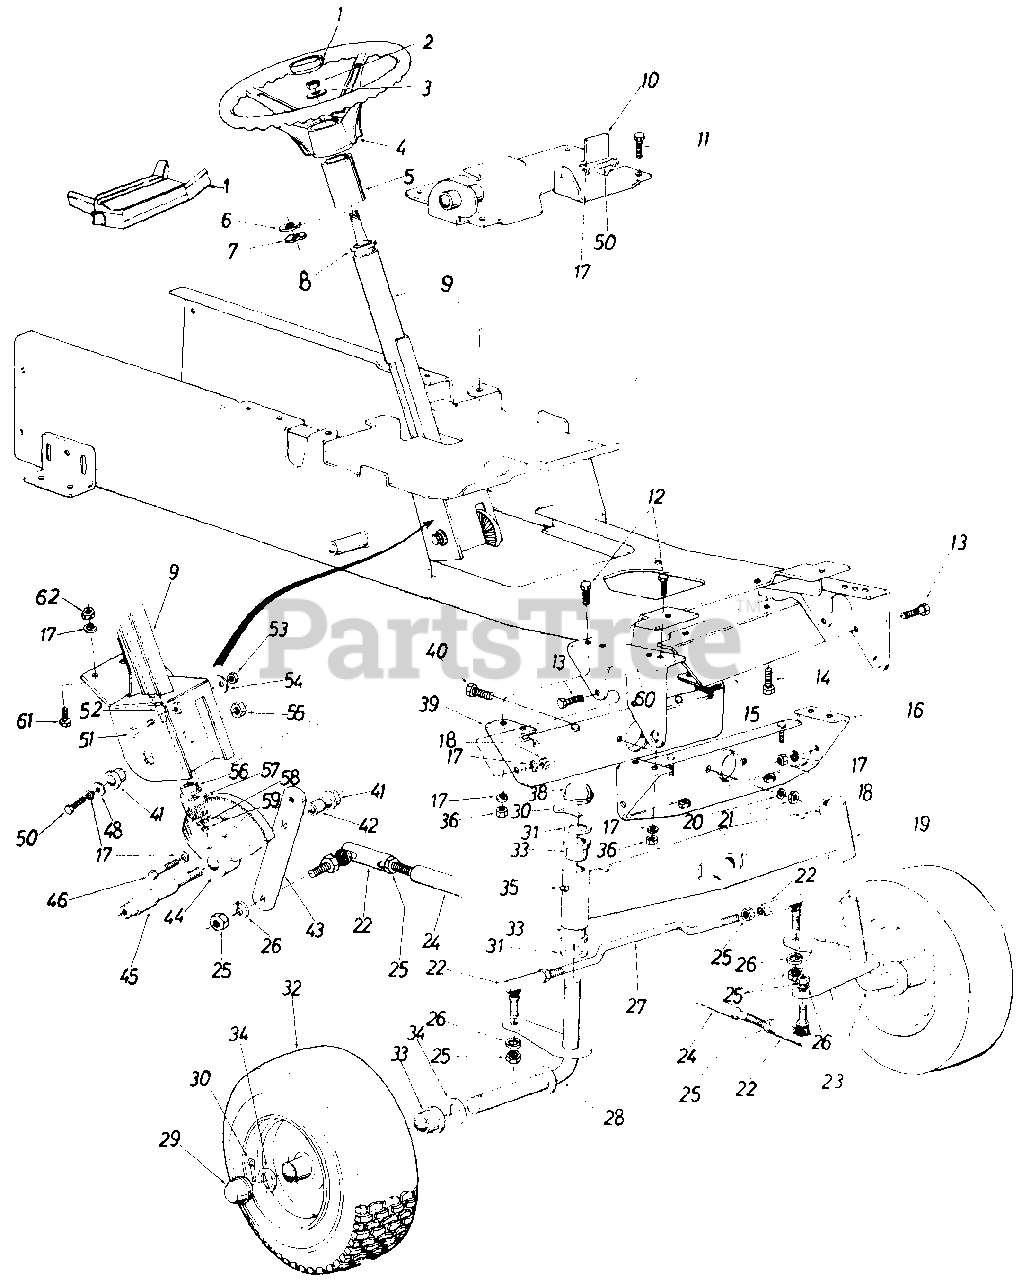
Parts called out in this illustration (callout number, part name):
1	Steering Wheel Cap
2	Hex Cent. L-Nut 5/16-18 Thd.
3	Bell-Wash.
4	Steering Wheel
5	Steering Tube - Outer
6	Double "D" Fl-Wash.
7	Wave Wash. .660" I.D. x .88" O.D.
8	Ball Brg. .63" I.D. x 1.38" O.D.
10	Dash Panel Base Plate Ass'y.
11	Hex Self-Tap Scr. 3/8-16 x .75" Lg.
12	Hex Bolt 3/8-16 x 1.50" Lg.
13	Hex Bolt 3/8-16 x 1.00" Lg.
14	Hex Wash. S.F. Tap Scr. 3/8-16 x 1.25" Lg.
15	Dust Shield
18	Hex Nut 3/8-16 Thd.
19	Pivot Bar Ass'y.
20	Bell-Wash. 3/8" I.D.
21	Hex Cent. L-Nut 3/8-16 Thd.
22	Drag Link End
23	Axle Ass'y.- L.H.
24	Drag Link
25	Hex Nut 1/2-20 Thd.
26	L-Wash. 1/2" I.D.
27	Tie Rod
28	Axle Ass'y.- R.H.
29	Hub Cap
30	Cotter Pin 3/16" Dia. x 1.50" Lg.
31	Fl-Wash. 1.00" I.D. x 1.62" O.D.
33	Flange Brg. .757" I.D.
34	Fl-Wash. .635" I.D. x 1.12" O.D.
35	Grease Fitting
36	Hex Nut 3/8-16 Thd.
38	Dust Cover
40	Hex Bolt 3/8-16 x 2.50" Lg.
41	Flange Brg. w/Flats .753" I.D.
42	Steering Gear Shaft Spacer
43	Steering Arm
44	Bevel Gear
45	Steering Gear Shaft
46	Hex Bolt 3/8-16 x 1.50" Lg.
48	Fl-Wash. .406" I.D. x 1.25" O.D.
50	Hex Bolt 3/8-16 x .75" Lg.
51	Nylon Hex Bolt 3/8-16 x 1.25" Lg.
52	Steering Shaft
53	Hex Jam Nut 3/8-16 Thd.
54	Bell-Wash. .400" I.D. x 1.13" O.D.
55	Hex Ins. L-Nut 1/2-20 Thd.
56	Hex Flange Brg. .630 I.D.
57	Pinion Gear
58	Fl-Wash. 3/8" Dia.
59	Hex Cent. L-Nut 5/16-24 Thd.
62	Hex Nut 3/8-24 Thd.
